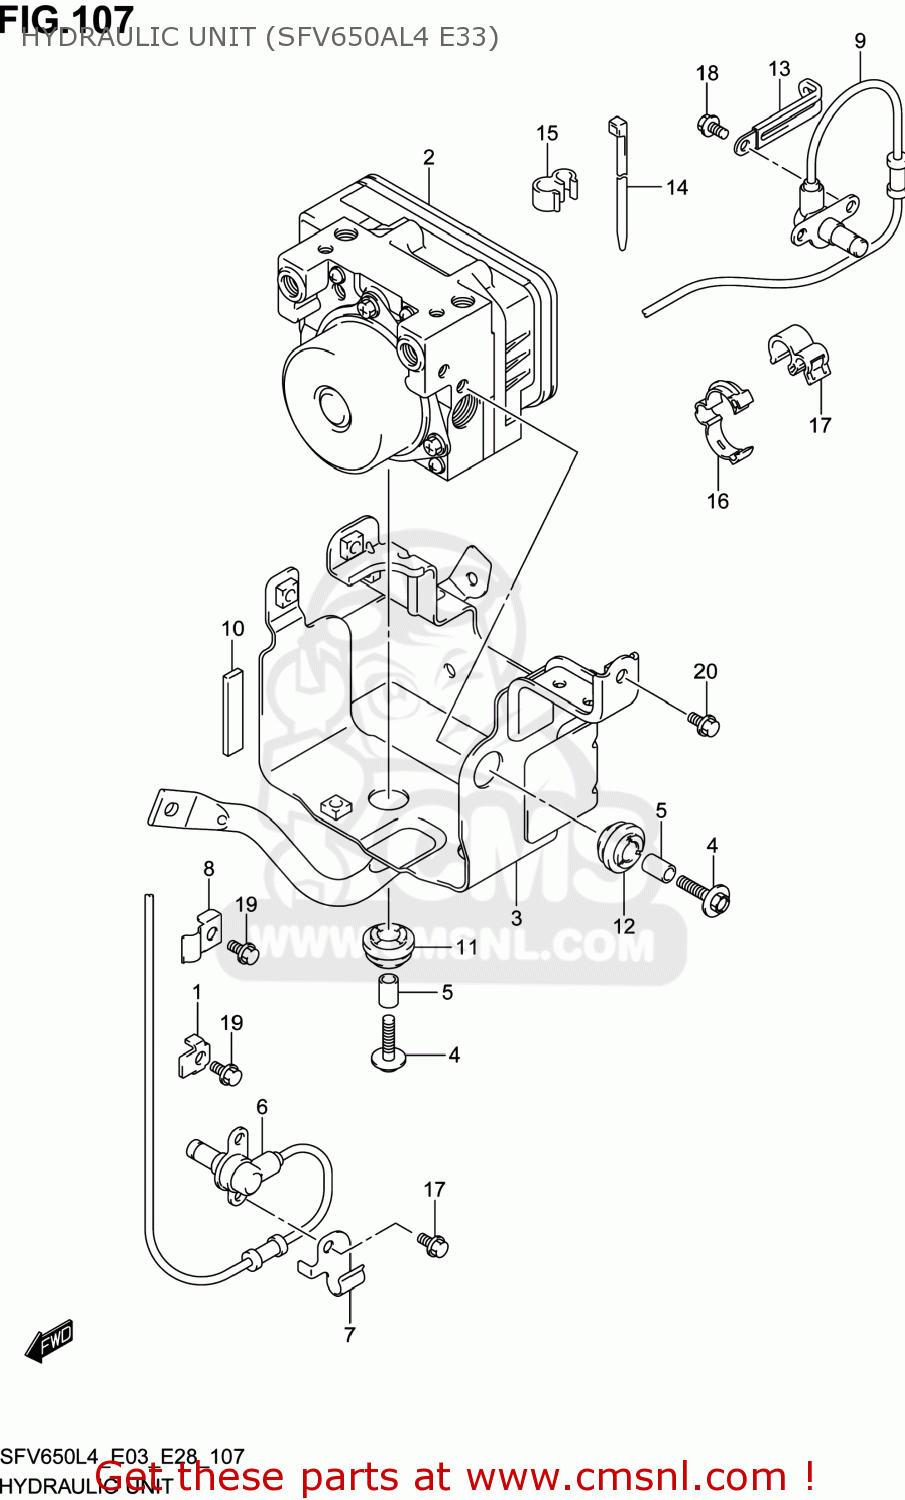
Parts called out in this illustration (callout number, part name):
1	GUIDE,SENSOR LEAD
2	UNIT ASSY,HYDRAULIC ABS
3	HOLDER,HYDRAULIC UNIT ABS
4	BOLT,HYDR UNIT MTG
5	SPACER,HYDR UNIT MTG
6	SENSOR,FR WHEEL ABS
7	CLAMP,SENSOR LEAD FR NO.1
8	CLAMP,SENSOR LEAD FR NO.3
9	SENSOR,RR WHEEL ABS
10	TAPE,ABS UNIT HOLDER
11	RUBBER
12	RUBBER
13	CLAMP(L:45)
14	CLAMP(L:145)
15	CLIP
16	CLAMP
17	CLAMP
18	BOLT
19	BOLT
20	BOLT
